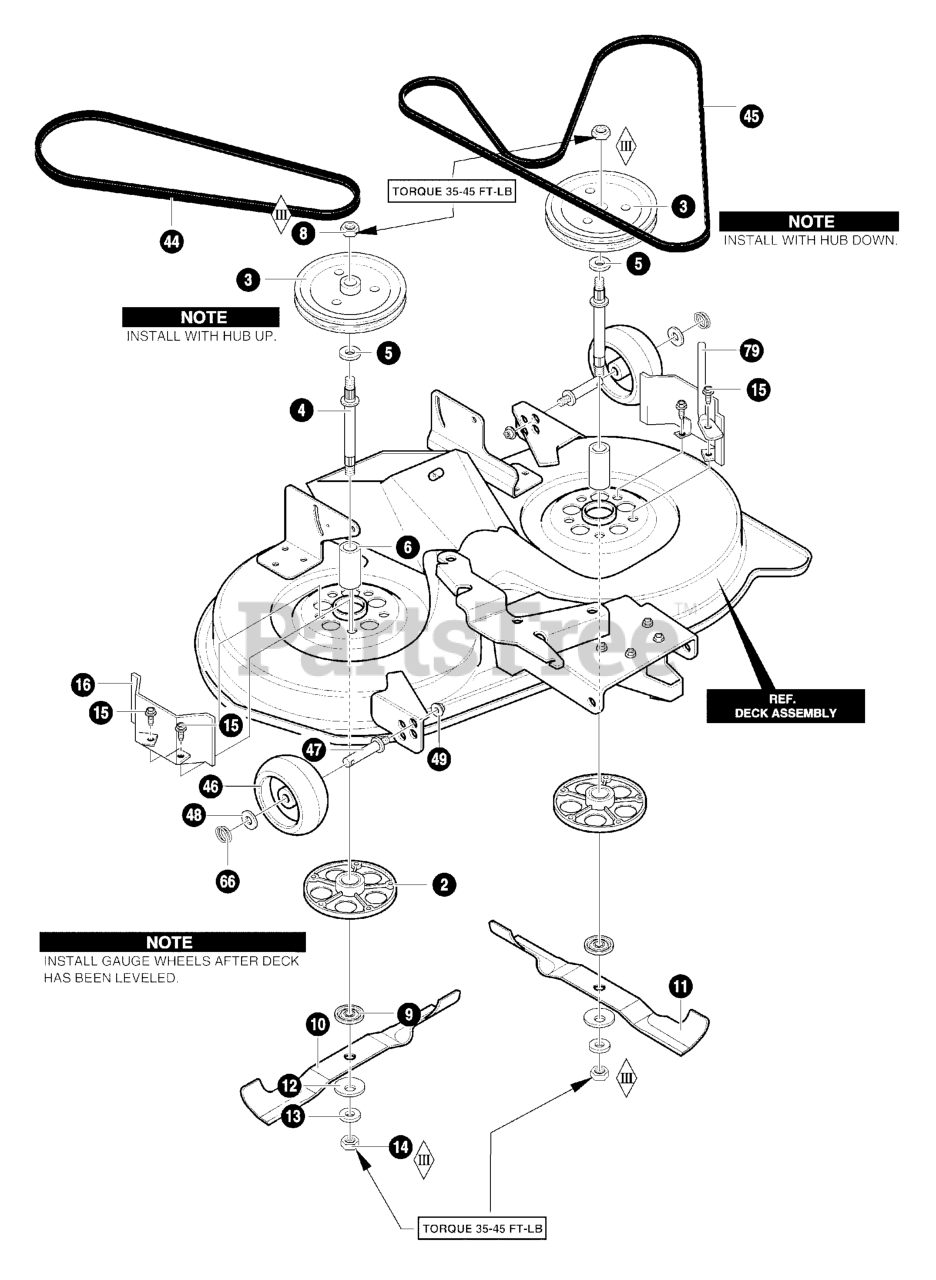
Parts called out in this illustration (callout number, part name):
2	ASM. JACKSHAFT HOUSING W/VENTS
3	PULLEY, DECK
4	JACKSHAFT
5	WASHER, FLAT
8	NUT, 9/16-18 CTRLK
9	ADAPTER, DECK/BLADE
10	BLADE LH
11	BLADE RH
12	WASHER, BELLEVILLE
13	WASHER, FLAT
14	NUT, 9/16-18
15	SCREW, 3/8-16 x 1.00
16	PULLEY COVER
45	BELT, V
46	WHEEL, GAUGE
48	FLATWASHER
49	NUT, 3/8-16
66	CIRCLE PIN
79	ZINC ROD BELT GUIDE
